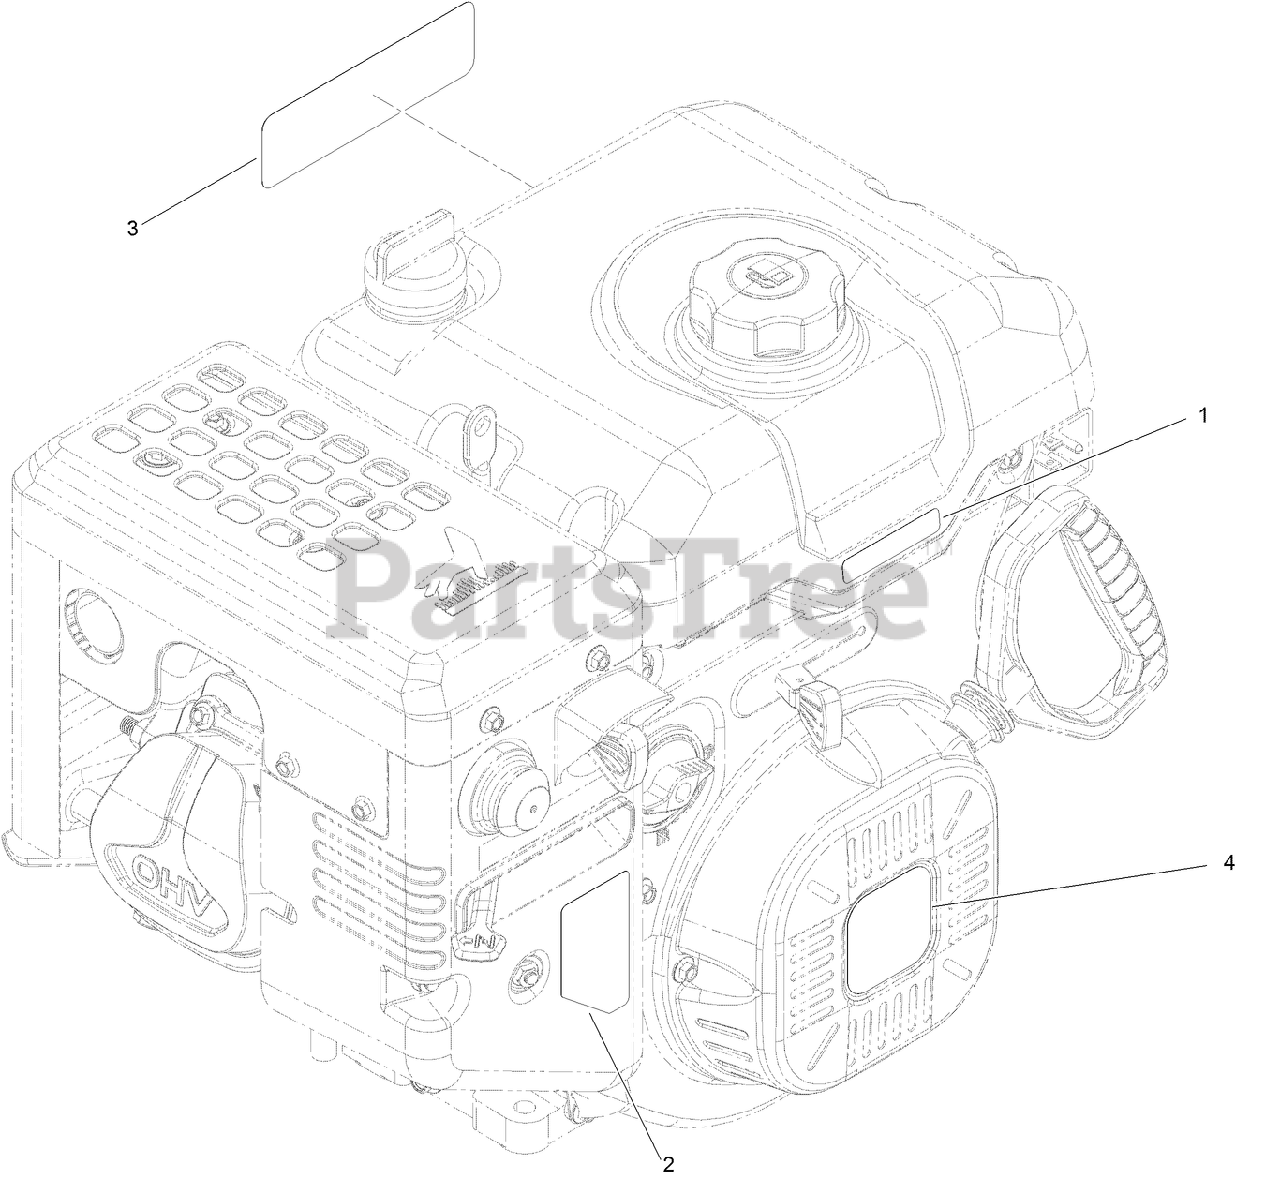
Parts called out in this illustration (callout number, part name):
1	DECAL-THROTTLE
2	DECAL-CONTROL, ENGINE
3	DECAL-ENGINE SERIES, G250
4	DECAL-RECOIL, G250
